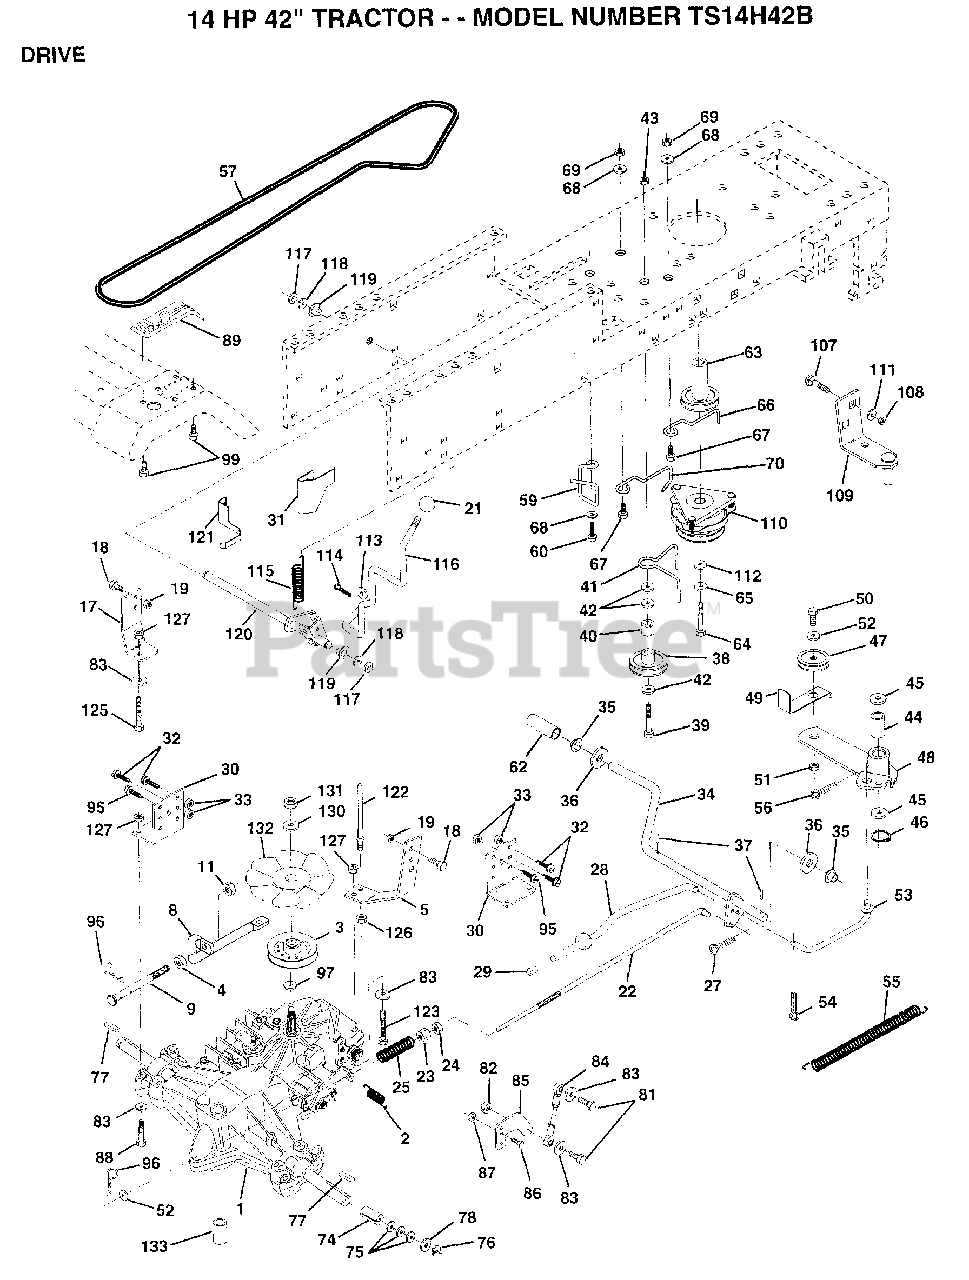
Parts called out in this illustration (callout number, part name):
2	SPRING RET BRAKE
4	JAM NUT TI
5	STRAP TORQ RH HYD
11	NUT
17	STRAP TORQ LH HYD
18	BOLT
19	NUT
21	KNOB T (1/2-HOLE)
23	NUT
24	NUT
25	SPRING ROD LT
27	COTTER PIN
28	BRAKE PARK ROD
29	PLUNGER CAP T
30	TRANSAXLE MTG BKT
31	"KEEPER,BELT LH T"
32	BOLT
33	NUT
35	NYLON BEARING
36	WASHER LT
38	PULLEY.IDLER.FLAT
39	BOLT
40	SPACER T
41	BELT KEEPER LT
42	WASHER
44	"LY, BEARING"
45	WASHER LT
46	KLIP RING
48	ARM IDLER
49	RETAIN BELT
52	WASHER
53	"LINK, CLUTCH T"
54	COTTER PIN
55	"SPRING, RETURN LT"
56	COTTER PIN
57	"BELT.GD DRV 82"""
59	KEEPER BELT CNTSP
60	SCREW
62	PEDAL COVER T
63	PULLEY CLU ELEC
65	LOCKWASHER
66	KEEPER BELT ENGLH
67	BOLT
68	WASHER
70	"KEEPER,BLT ENG LT"
74	SPACER SPLIT
75	WASHER
76	E-RING LT
77	SQUARE KEY
78	WASHER
81	BOLT
82	NUT
83	WASHER M
84	ROD.TIE.BALL.4.75
85	ARM CONTROL HYDRO
86	SCREW CAP 5/16-18
87	NUT
88	BOLT HEX
95	SCREW
96	RETAINER M
97	WASHER LT
99	SCREW HEXWSH H-L
107	BOLT
109	BRACKET.ASM.MTG
111	WASHER T
112	WASHER
113	WASHER
114	PIN COTTER 1/8
115	"SPRING,TORSION"
116	ROD SHIFT FEND LT
117	KLIP RING
118	WASHER D
119	BUSHING
121	KEEPER BELT LH
122	BOLT KEEPER RH
125	HEX BOLT
126	NUT
127	NUT
130	WASHER BELLEVILLE
131	NUT NYLON 1/2-20
132	"FAN 7"" HYDRO"
133	"LINE FUEL HYD 4"""
